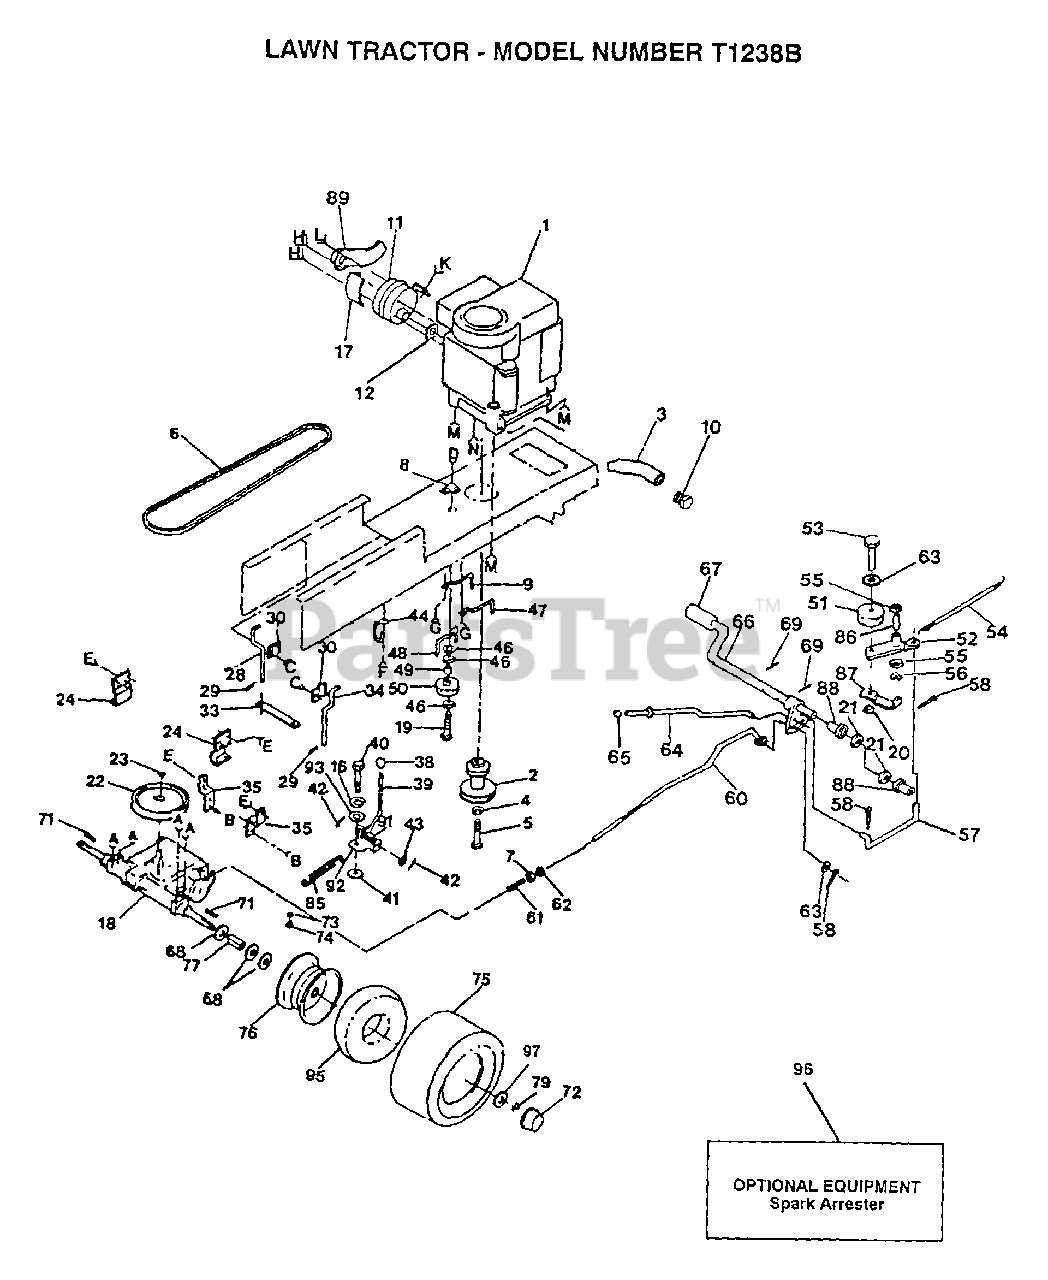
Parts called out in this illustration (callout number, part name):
1	ENGINE BRIGGS AND STRATTON
4	LOCKWASHER
5	BOLT
6	BELT-V.90.0.GD.DR
7	NUT
8	CLIP T
9	KEEPER BELT ENGLH
11	MUFFLER LTV
16	LOCKWASHER
17	SHIELD HEAT LTV
19	BOLT
21	WASHER LT
22	PULLEY TRANS
24	BRACKET LT
28	KEEPER BELT LH
29	SPRING.RETAINER
30	CLAMP LT
33	STRAP LOCATOR
34	KEEPER BELTRH
35	STRAP TORQUE
38	CONTROL KNOB LT
39	ROD SHIFTER
41	WASH-SHFT PLT LT
42	PIN COTTER 1/8
43	WASHER
46	WASHER
47	"KEEPER,BLT ENG LT"
48	BELT KEEPER LT
49	SPACER T
50	PULLEY.IDLER.FLAT
52	ARM IDLER
54	"SPRING, RETURN LT"
55	WASHER LT
56	KLIP RING
57	"LINK, CLUTCH T"
58	COTTER PIN
60	BRAKE ROD LT
61	SPRING ROD LT
62	NUT
63	WASHER
67	PEDAL COVER T
68	WASHER
71	SQUARE KEY
72	HUB CAP
73	VALVE CAP
74	VALVE STEM LT
77	SPACER LT
79	E-RING LT
86	"LY, BEARING"
87	RETAIN BELT
88	NYLON BEARING
89	DEFLECTOR MUFFLER
91	SPRING LT
92	PLATE SHIFT LT
93	WASHER LT
95	TUBE.18X9.5-8
97	WASHER
